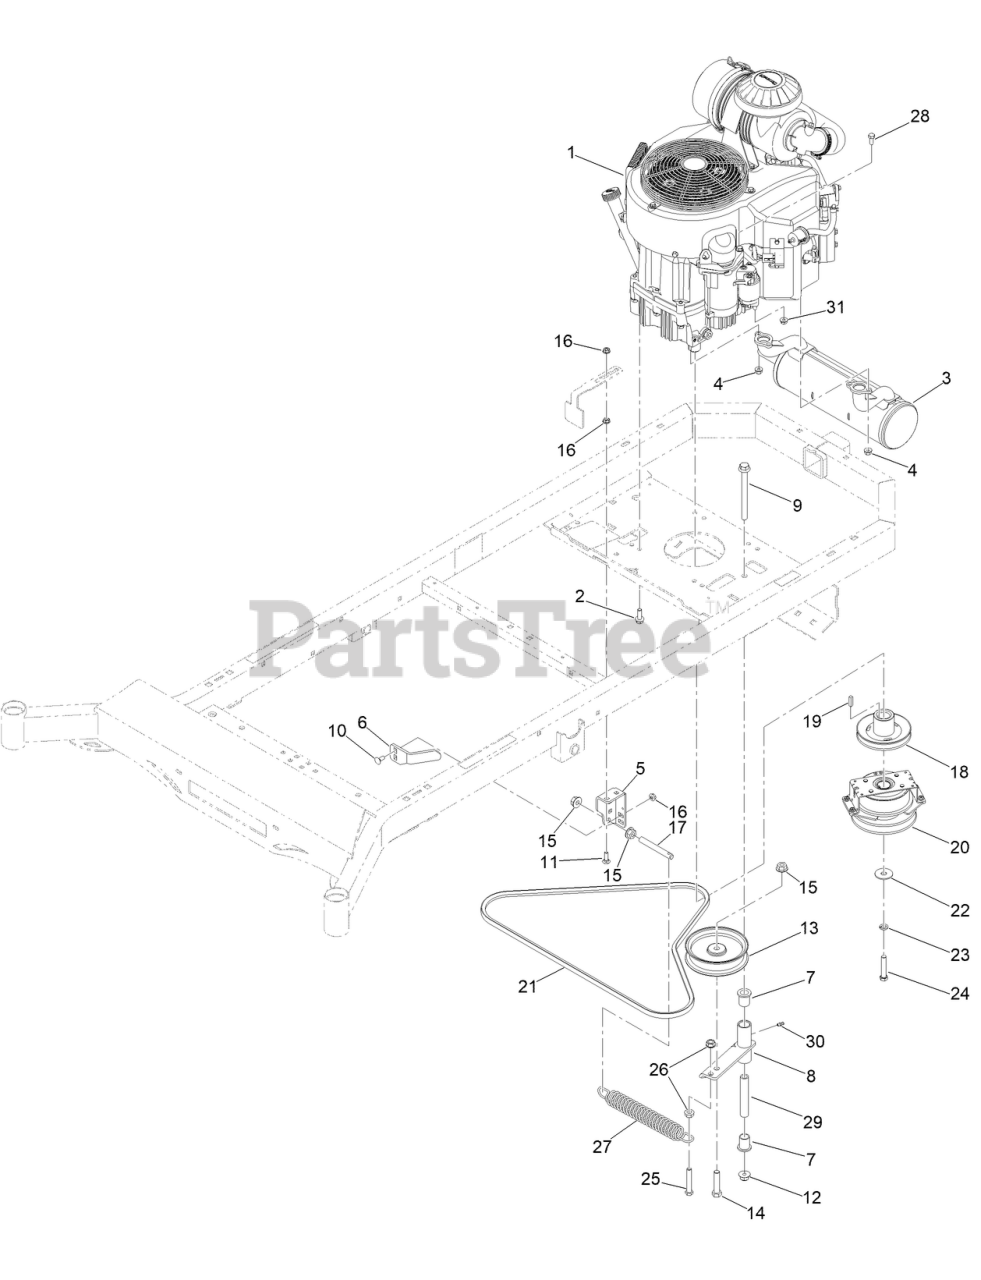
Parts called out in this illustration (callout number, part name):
1	KAWASAKI FX801V ENGN
2	3/8-16 X 1-1/8 IND HWH W/SERR TRI LOB ZY
3	EXHAUST SYSTEMKAWI FX801/FX850/FX850EFI
4	NUT-HF
5	MWR PUMP IDLER TENSIONING BRKT BLACK
6	2021 TTQ MOWER OGURA CLUTCH BRACKET
7	3/4IN ID X15/16IN OD X 1-1/8IN FLNG BUSH
8	MWR PUMP IDLER ASSY BLACK
9	1/2-13 X 5-1/2 HEX FLANGE BOLT GR 8 ZY
10	BOLT-CARR
11	BOLT-CARR
12	NUT-LOCK
13	5-3/4IN IDLER PULLEY 7/16IN SPACER ASSY
14	SCREW-HH
15	NUT-HHF
17	MWR PUMP IDLER SPRING TENSIONER
18	MWR HYDRAULIC PUMP DRIVE PULLEYA BELT
20	MWR TTQ OGURA CLUTCH
21	MWR PUMP BELT RT A X 68.25IN EFF LNGTH
22	1/2IN X 1-5/8 BELLEVILLE CUP WASHER YZ
23	WASHER-LOCK
24	TTQ CLUTCH BOLT
26	NUT-HF
27	MWR DECK SPRING
28	M8-1.25 X 20MM HEX FLANGE BOLT ZINC 10.9
29	MWR INNER IDLER SPACER
30	1/4IN DRIVE TYPE GREASE FITTING YZ
31	NUT-HF
